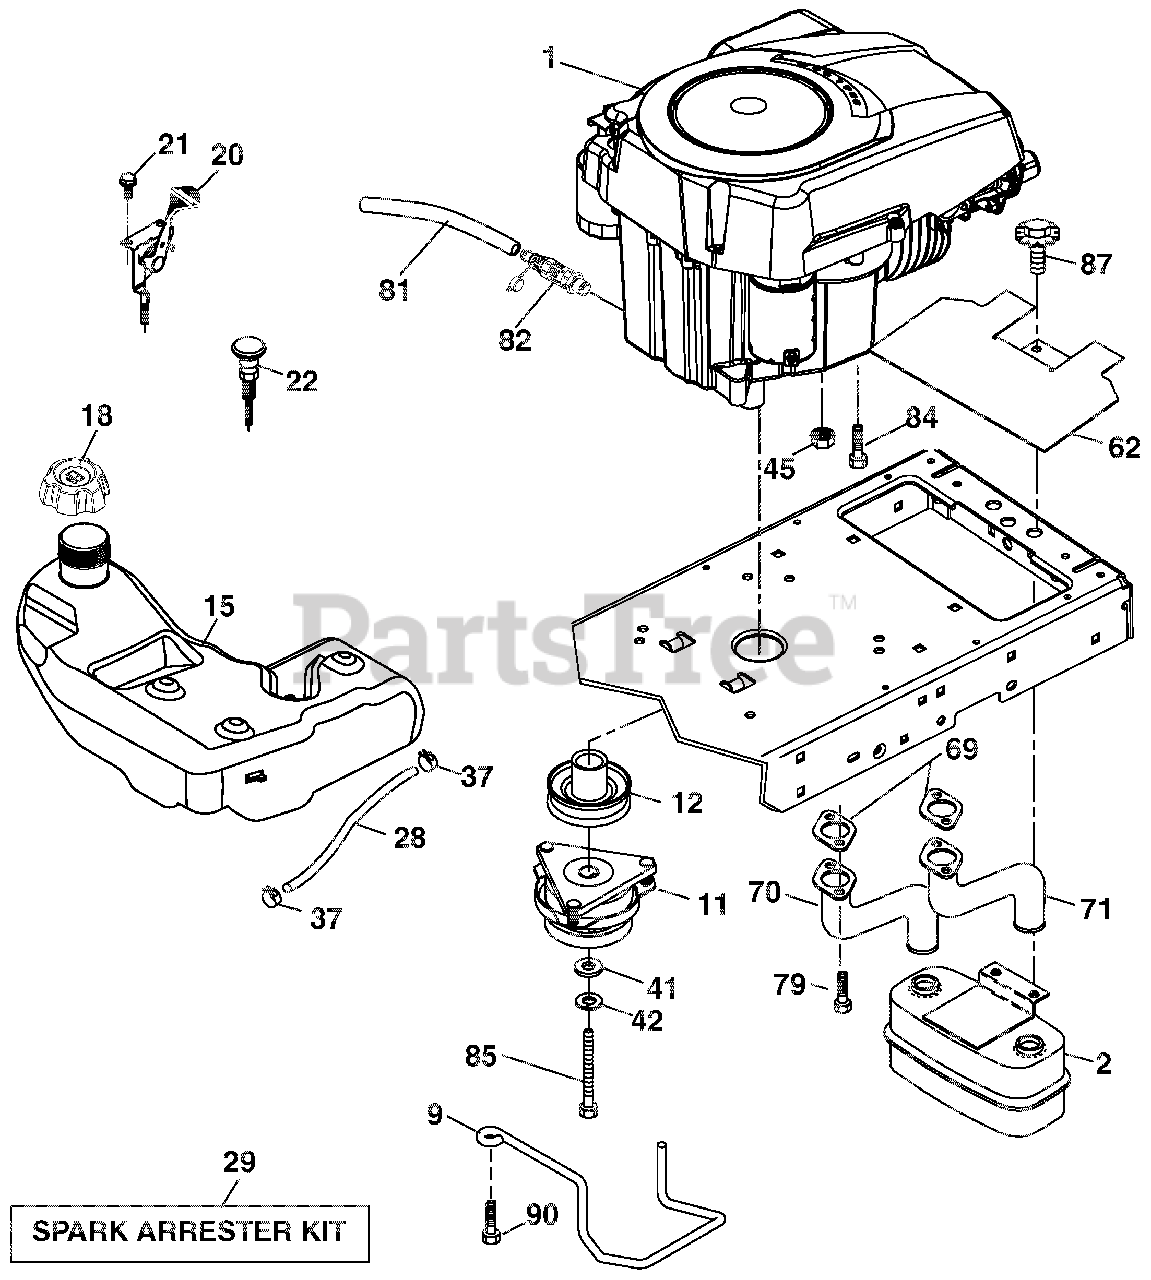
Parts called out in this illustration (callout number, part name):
1	ENGINE KOHLER MODEL NO. SV715-0026(ORDER PARTS FROM ENGINE MANUFACTURER)
2	MUFFLER ASM.TWIN.LO-TONE
9	KEEPER.BELT.ENGINE.4.25"NSTG
11	CLUTCH.ELECTRIC.LT.1"CRANK
12	PULLEY.ENGINE.TUFFTORQE.1"CRK.
15	TANK.FUEL.SIDE-FILL.3.00 GA.
18	CAP FUEL
20	CONTROL.THROTTLE.COBRA.2001.BK
22	CONTROL.CHOKE.ERGO.45"BLK.P-IN
28	LINE.FUEL.64"REAR.EMIS.CA.LP
29	KIT.SPARK ARRESTOR(392390 B&S)
37	CLAMP.HOSE.BLK.
41	WASHER.1-1/2 ODX15/32 IDX.250
42	WASHER.LOCK.HVY HLCL.SPR.7/16
45	Nut, Keps Hex 1/4-20 unc
62	SHIELD.HEAT.MUFFLER.CV-INTEK
69	GASKET MUFFLER (ORDER FROM ENGINE MFGS)
70	PIPE.EXHAUST.LH.CV18/20
71	PIPE.EXHAUST.RH.CV18/20
79	SCREW.SOCKET HD.5/16-18 X .75
81	TUBE.DRAIN.OIL.EASY
82	VALVE OIL DRAIN
84	SCREW.3/8-16 X 1.SMGML.TAP/R
85	BOLT.HEX.7/16-20X4XGR5-1.5THR.
87	BOLT.5/16-18UNCX3/4 W/SEMS.BLK
90	SCREW.3/8-16X1.SMGML.TAP/R.BLK
